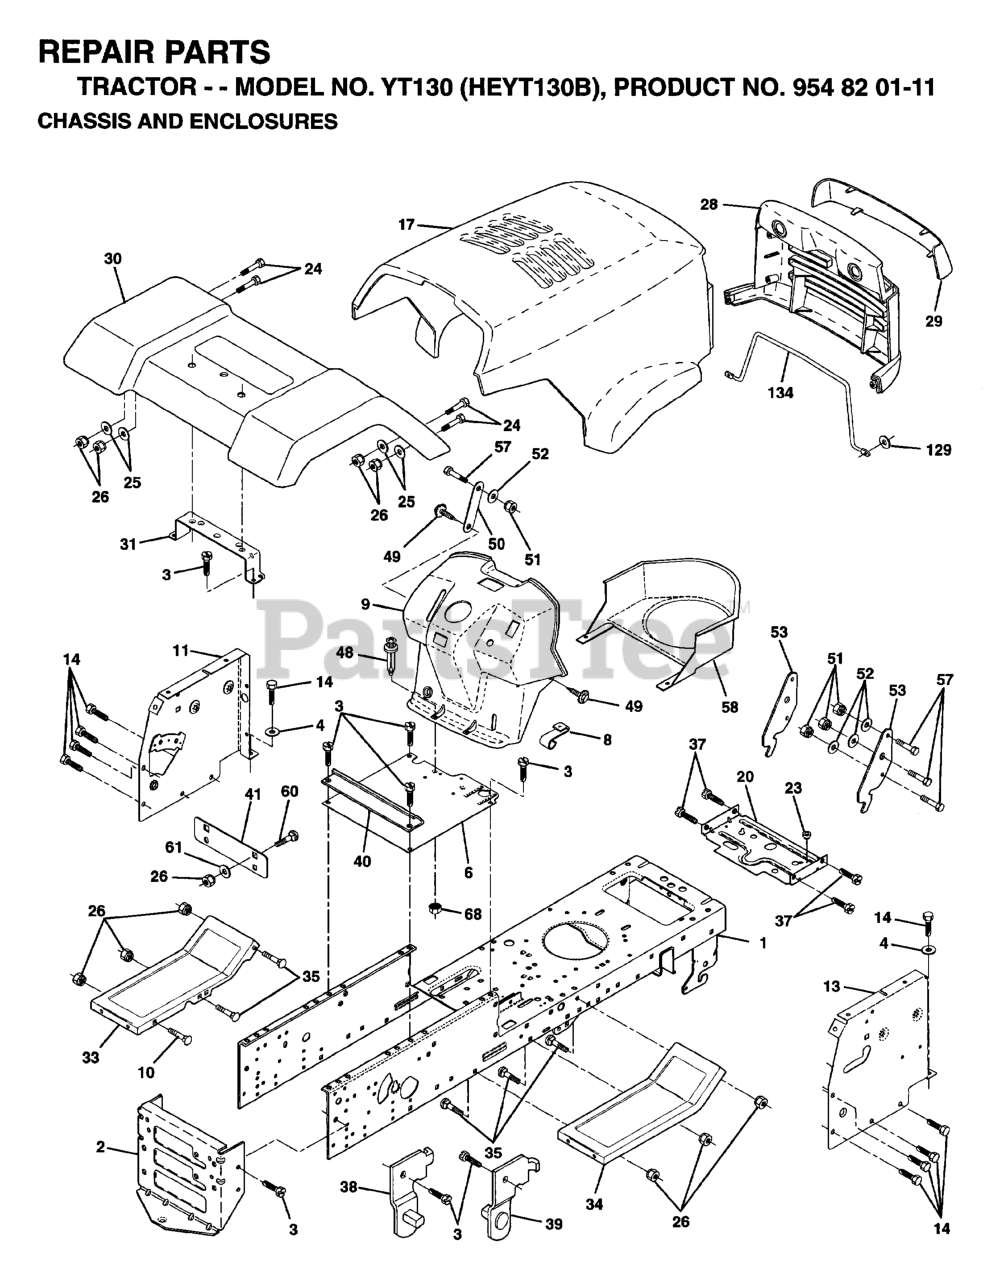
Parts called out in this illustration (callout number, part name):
1	CHASSIS WELD 11GA.95
2	STRETCH DRAWBAR
3	SCREW
4	Washer 13/32 X 3/4 X 16 Ga.
6	SADDLE LT FENDER
8	CLIP,INSULATOR
10	BOLT D
13	PANEL.DASH.RH
17	HOOD LT/PL HUSQVARNA
20	PLATE MTG BATTERY FUEL TAND
23	BUSHING.SNAP.NYL.BLK.
25	WASHER
26	NUT
28	GRILLE LT/PL HUSQVARNA
29	LENS LT/PL HUSQVARNA
30	FENDER
31	BRACKET.SUPPORT.FENDER
33	FOOT REST LH
34	FOOTREST RH
37	Screw 5/16-18 x 1/2 Hex, Self Tapping 5/16-18 x 1/2
38	BRACKET LH PIVOT
39	BRACKET RH PIVOT
41	PLATE
48	RIVET PUSH
49	SCREW HEX CRT
51	LOCKNUT.NYLOC.1/4-20
53	BRACKET PNT PICK OFF LT/PL
57	BOLT
58	AIR DUCT P/L/LT
60	Bolt - Rd. Hd. Sq. Neckiage 3/8 16 x 3/4
61	Washer 1 17/32 X 7/8 X 16 Ga
68	NUT
134	ROD SUPPORT HOOD LT/PL HUSQ
